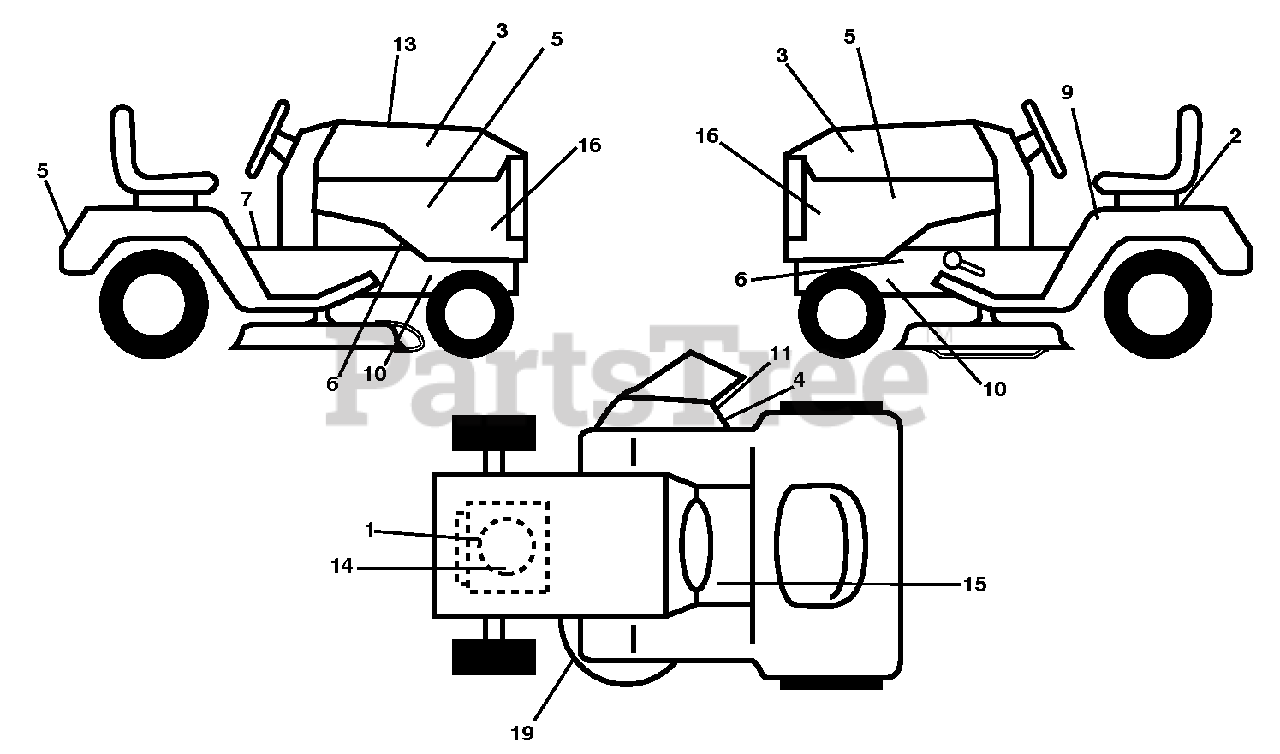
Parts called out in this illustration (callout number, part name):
1	DECAL.ENGINE.WARNING
2	DECAL BTRY SYMBOLS
4	DECAL.DFLCTR.WARNNG.CTFNGR.SYM
5	DECAL HOOD
6	DECAL.WARNING.SERVCE/FIRE
7	DECAL.PARKING.BRAKE.SADDLE.LT
9	DECAL.READ.OWN.MAN.SYMBOL.LT
10	DECAL.CHASSIS.HOT.MUFFLER
11	DECAL.CUTFINGER.CE.02
14	DECAL
15	DECAL.FNDR.SDLE.BRAKE.CLUTCH.6
19	DECAL.DECK.SCH.36,38,94.NONCR
